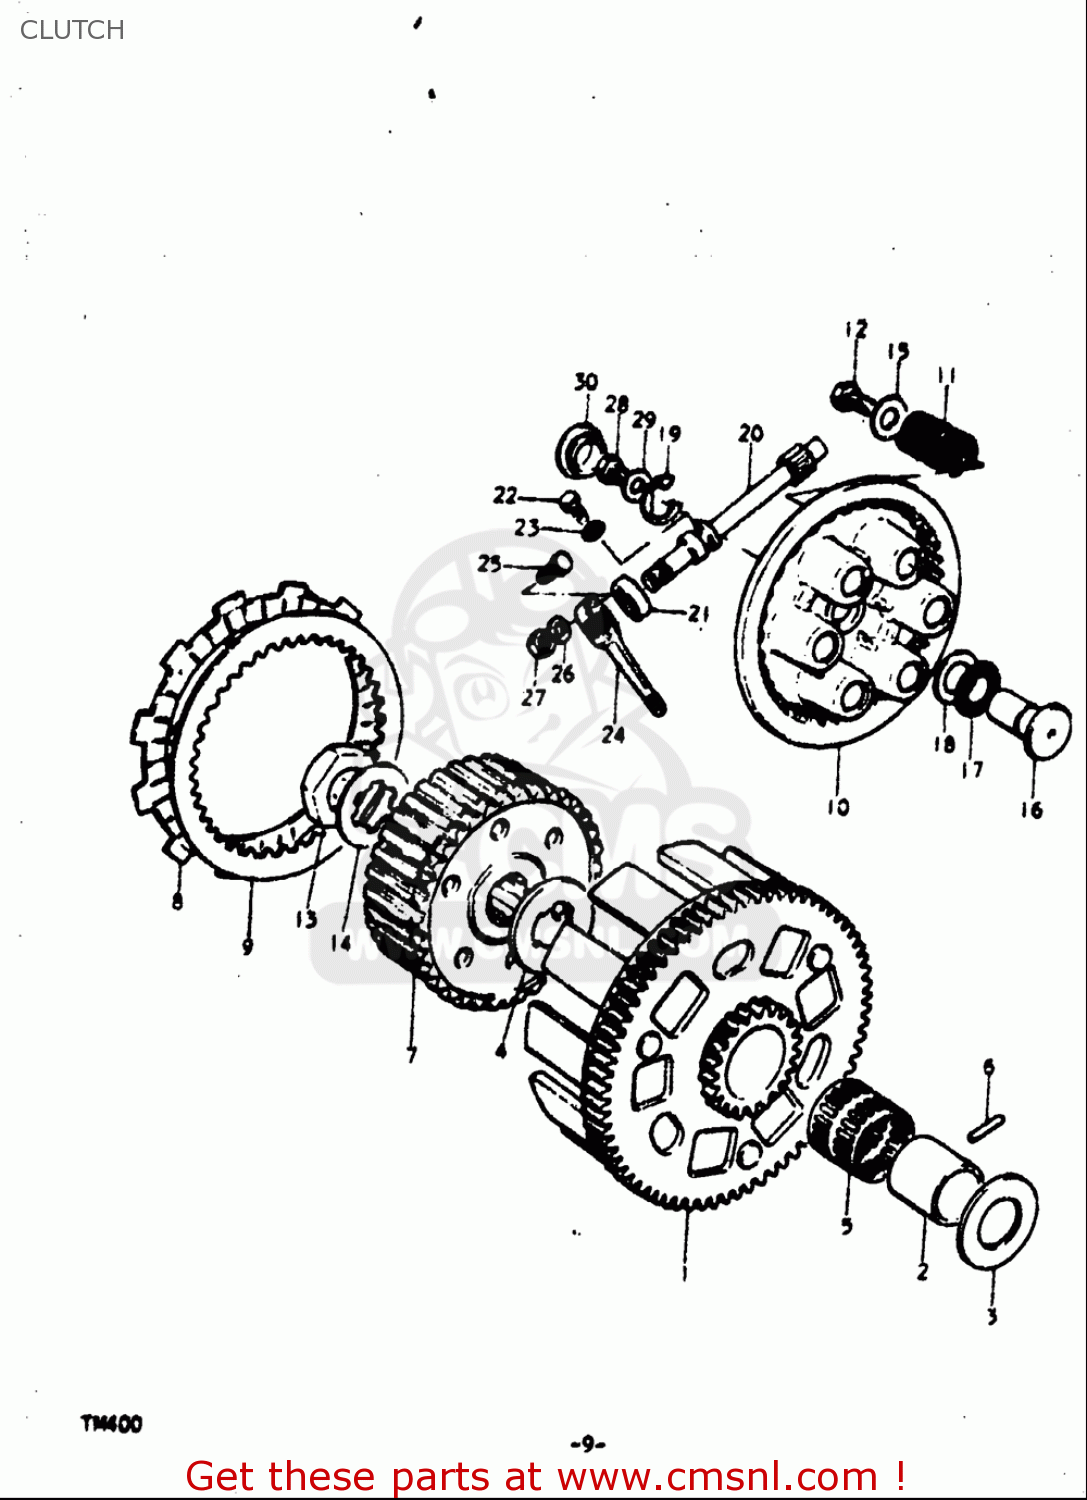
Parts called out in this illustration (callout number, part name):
2	SPACER
3	WASHER
5	BEARING
8	PLATE,CLUTCH DRIVE(T:3.5) (NAS)
9	PLATE,CLUTCH DRIVEN(T:2.0) (NAS)
10	DISC,CLUTCH PRESSURE
11	SPRING
12	BOLT
13	NUT
14	WASHER,LOCK
15	WASHER(6.5X20X1.6)
16	RACK,CLUTCH RELEASE
17	BEARING(15X28X2)
18	WASHER(15.5X28X1)
19	E RING
20	PINION,CLUTCH RELEASE
21	SEAL,OIL (12X22X9)
22	BOLT(6X12)
23	WASHER
24	ARM,CLUTCH RELEASE
25	BOLT
26	WASHER
27	NUT
29	GASKET(8.2X14X1) (NAS)
